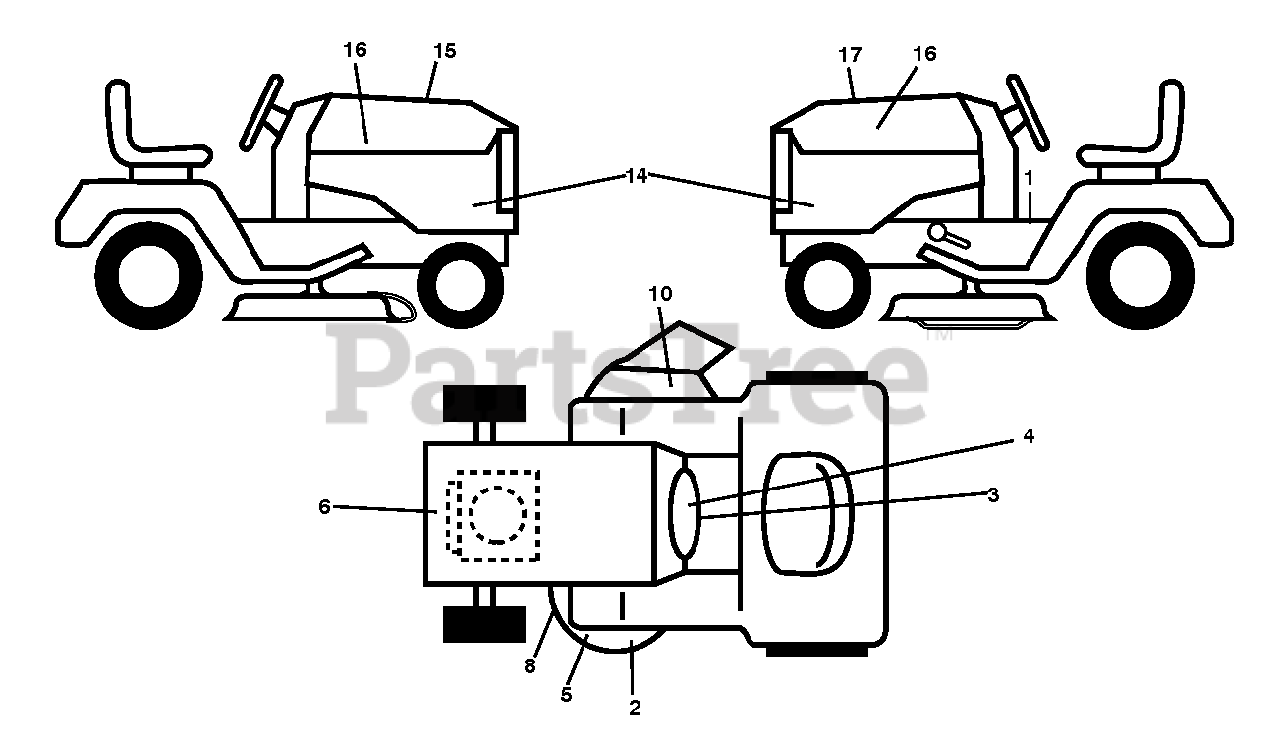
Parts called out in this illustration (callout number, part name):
1	DECAL TRACTOR LOWES DECAL DECA
3	Warning Decal, Spark Arrest
4	DECAL CARB EMISS.CA.HUSQ
5	DECAL.MOWER.CAUTION.TENSION.AR
6	DECAL.ENG.BS.INTK.24HP.382016
8	DECAL.MOWER.SCH.48/54.PREM
10	DECAL, DECK DEFLECTOR, WARNING
14	DECAL SIDE PANEL
15	DECAL TRACTOR SIDE PANEL SDPNL
16	DECAL.BADGE.170MM.TEXTLOGO.
17	DECAL.RPL.BSM44.INTK.48.GENTR
